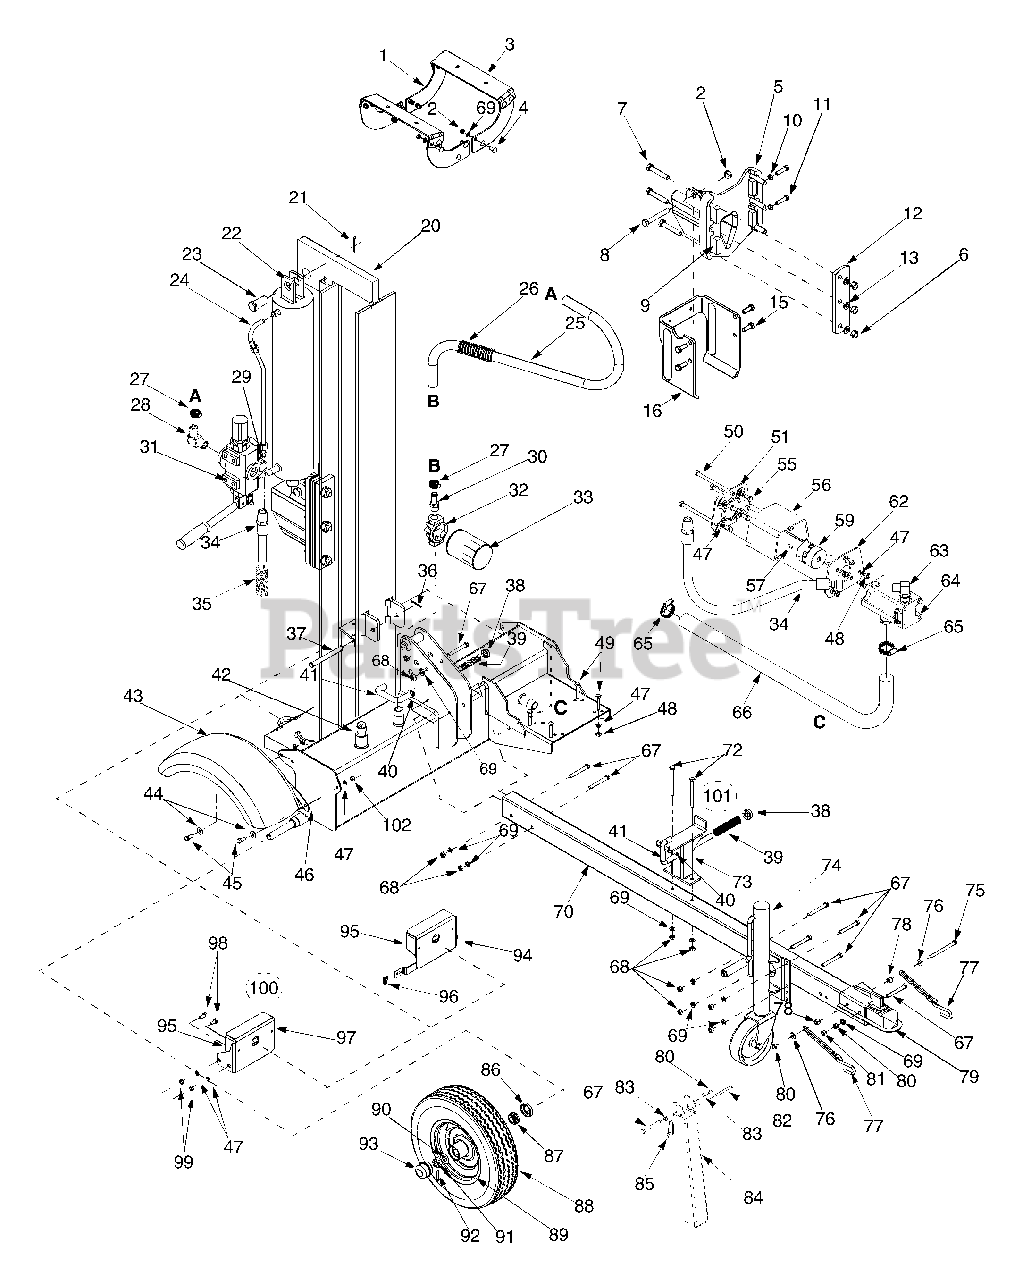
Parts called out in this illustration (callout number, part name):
4	Carriage Bolt 3/8-16 x 1.0
5	Wedge Assembly
6	Lock Nut 1/2-20
7	Hex Cap Screw 1/2-20 x 2.75
8	Hex Cap Screw 1/2-13 x 3.25
10	Hex Jam Nut 3/8-24
11	Hex Cap Screw 3/8-24 x 1.5
13	Lock Washer 1/2
15	Hex Screw 3/8-16 x 1.0
20	Beam Assembly
21	Cotter Pin
22	Kit Seal 5.0" for Best Metals cylinder 718-0313
22	Hydraulic Cylinder
22	Kit Seal 5.0" for XINGHUI cylinder 718-0313A
22	Kit Seal 5.0" for ENERGY cylinder 718-0313A
23	Clevis Pin
24	Hydraulic Tube
25	Return Hose 3/4" ID x 44" Lg.
26	Hose Guard
27	Hose Clamp 5/8"
28	Return Elbow
29	90 Degree Solid Male Adapter
30	3/4" Hose Adapter
32	Filter Housing
33	Oil Filter
34	High Pressure Hydraulic Hose
35	Hose Guard
36	Cotter Pin 1/8"
37	Hinge Pin 1/2 x 4.8" Lg.
38	Push Cap
39	Compression Spring 4"
40	Flat Washer.635 ID x.93 OD
41	Locking Rod
42	Vented Dipstick
45	Hex Cap Screw 5/16-18 x.875
46	Frame Assembly 7.0 Gal
47	Lock Washer 5/16
48	Hex Nut 5/16-24
49	Hex Cap Screw 5/16-24 x 1.75
50	Hex Scr. 5/16-24 x 5.0"
55	Hex Screw 5/16-24 x.75"
56	Coupling Shield
57	Key 1/4" x 2.00"
57	Key 3/16" x .75"
59	Flexible Coupling 1.00 x .437
63	Adapter 7/8-14
64	Gear Pump (16 gmp)
64	Pump Kit
64	Gear Pump (15 gpm)
65	Hose Clamp
66	Suction Hose
67	Hex Cap Screw 3/8-16 x 3.0
68	Hex Nut 3/8-16
69	Lock Washer 3/8
72	Hex Cap Screw 3/8-16 x 4.0
74	Adjustable Jack Stand
75	Hex Cap Screw 3/8-16 x 4.25
76	Flat Washer.385 ID x.870 OD
77	Chain
78	Spacer
79	Hitch Coupler
80	Lock Nut 3/8-16
81	Jam Nut, 3/8-16
82	Clevis Pin
83	Flat Washer
86	Bearing Seal
87	Bearing Cone
88	Wheel Assembly
90	Flat Washer.76" ID x 1.5" OD
91	Slotted Nut 3/4-16
92	Cotter Pin 5/32" x 1-1/4" Lg.
93	Hub Cap
96	Tinn Clip Nut, 1/4-20
99	Hex Nut 5/16-24
100	Taillight Kit
